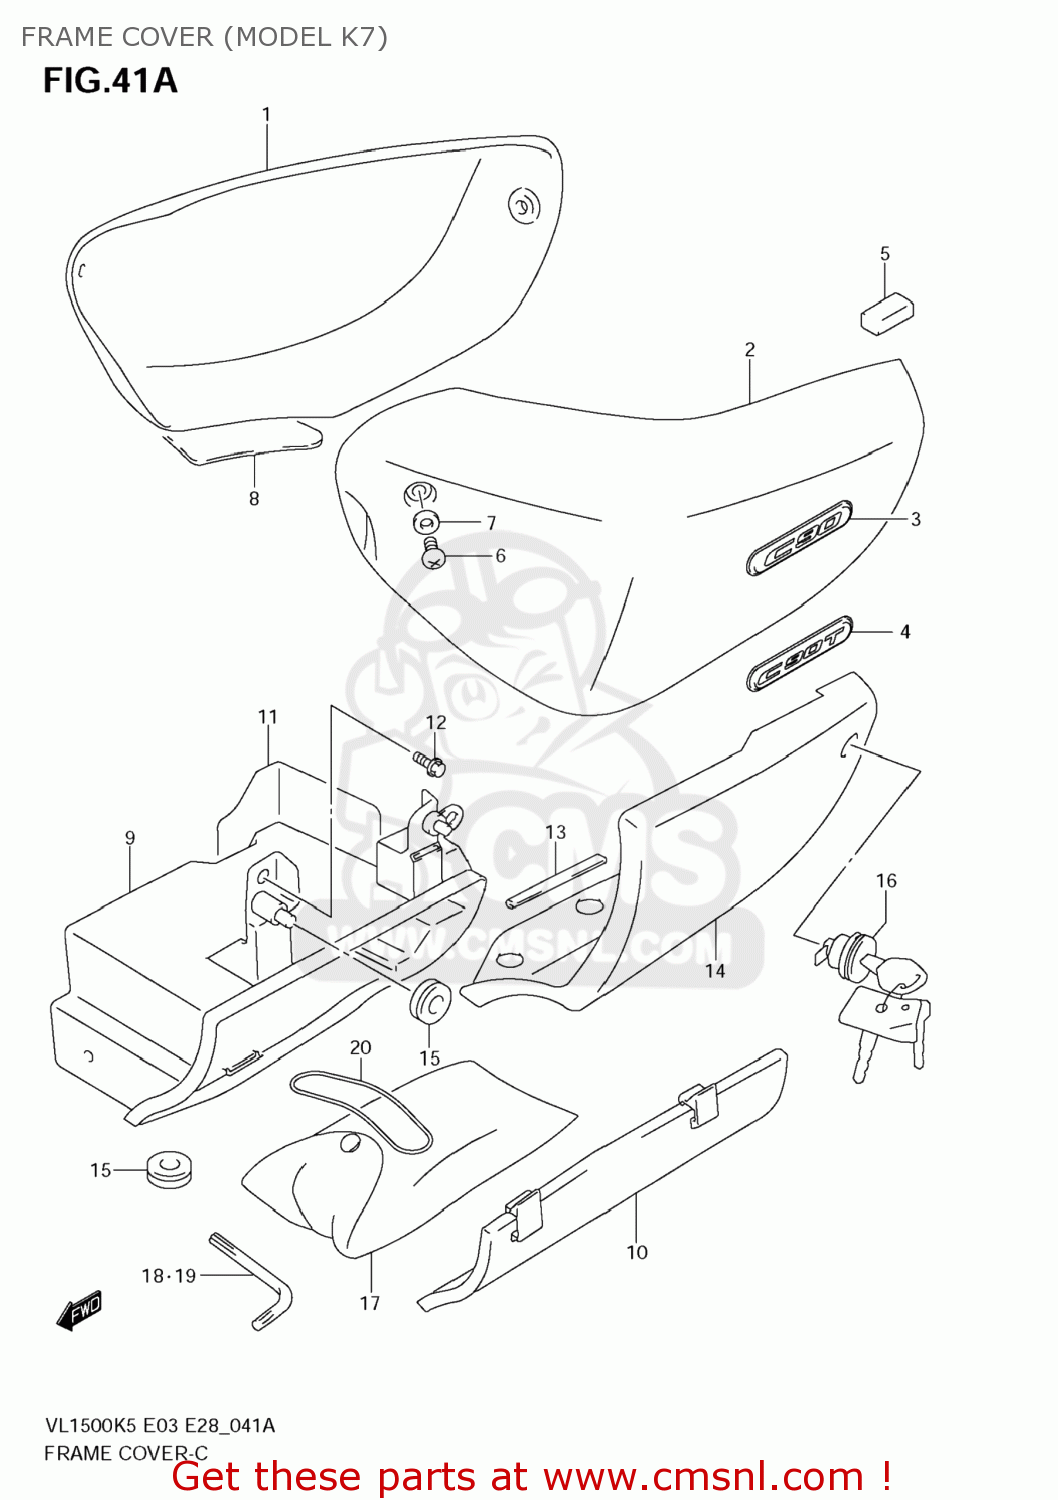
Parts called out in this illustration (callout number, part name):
1	COVER,FRAME,R(BLACK)
2	COVER,FRAME,L(BLACK)
3	EMBLEM,C90
4	EMBLEM,C90T
5	CUSHION,FRAME COVER
6	SCREW(6X16)
7	WASHER(6.5X15X1.0)
8	SHIELD,FRAME COVER,R
9	BODY,TOOL HOLDER
10	CAP,TOOL HOLDER
11	SHIELD,TOOL HOLDER BODY
12	BOLT(6X16)
13	MOLDING,FRAME COVER,L
14	COVER,TOOL HOLDER
15	CUSHION
16	LOCK SET,COVER
17	TOOL ASSY
18	SPANNER,HEXAGON(6)
19	HEXAGON SPANNER,5
20	O RING(D:3.5,ID:61)
